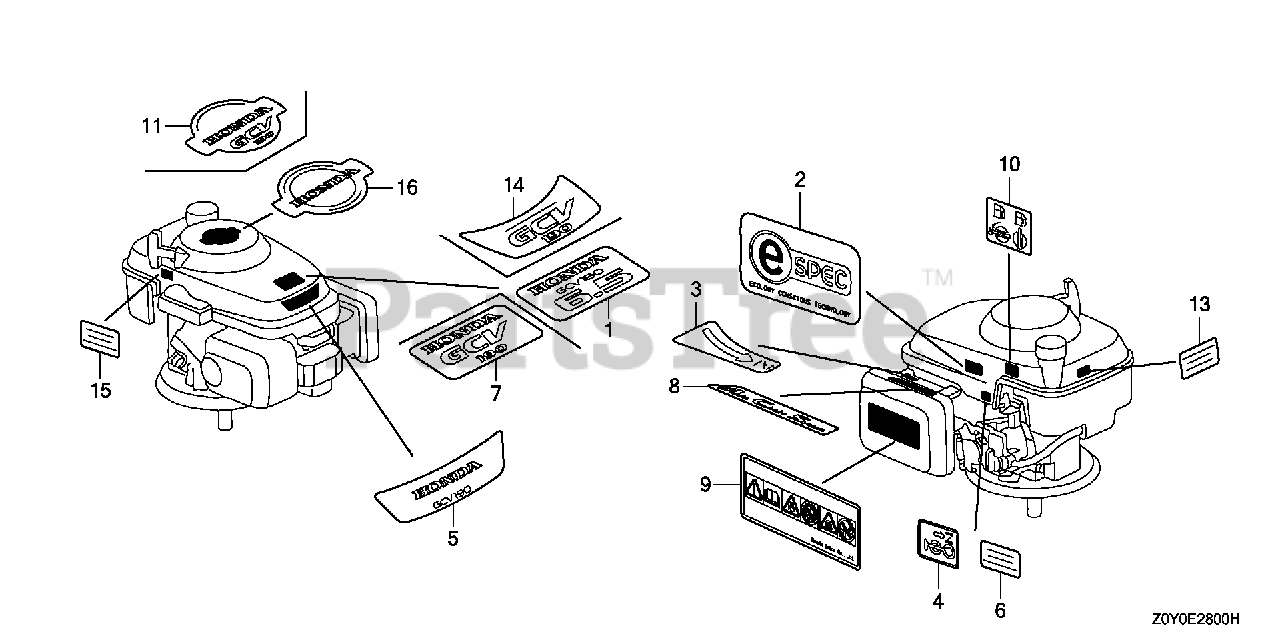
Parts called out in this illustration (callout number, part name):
1	MARK, EMBLEM (GCV190)
4	MARK, CHOKE
6	LABEL, WARNING (NOT CERTIFIED FOR SALE)
